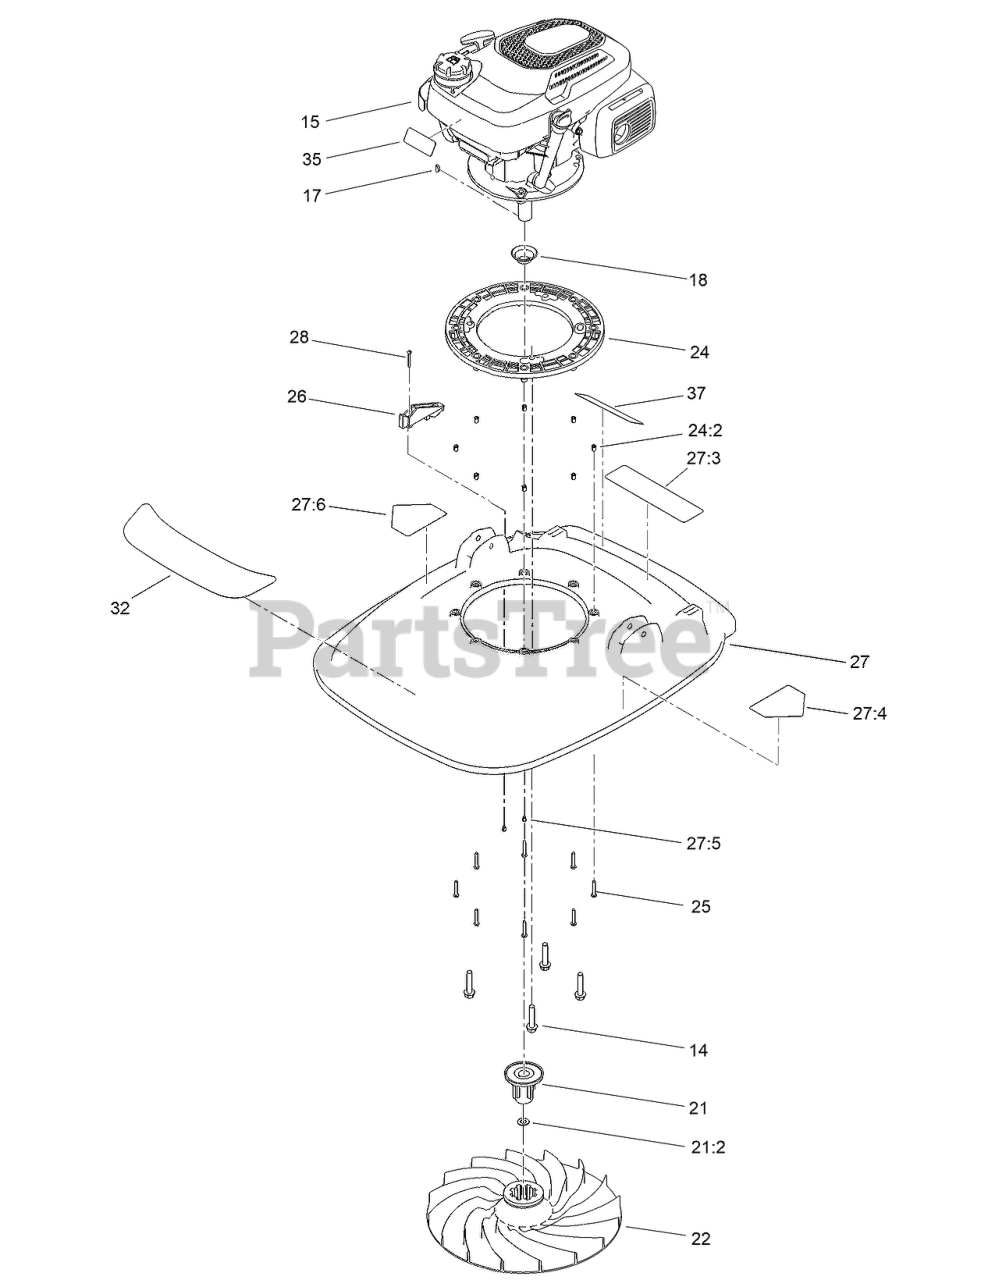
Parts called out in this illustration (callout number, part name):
14	SCREW-TAPTITE
15	ENGINE-HONDA (GCVX170)
17	KEY-WOODRUFF
18	PROTECTOR-SEAL, OIL
21	DRIVE AND SPACER ASM
21:2	WASHER-PLAIN
22	IMPELLER
24	FRAME-ENGINE
24:2	INSERT-BRASS
25	SET-SCREW
26	BRACKET
27	DECK ASM
27:3	DECAL-WARNING
27:4	DECAL-DANGER
27:5	INSERT
27:6	DECAL-DANGER
28	SCREW
32	DECAL-HOVER PRO
35	DECAL-WARNING, ETHANOL
37	DECAL-ARRESTOR, SPARK
